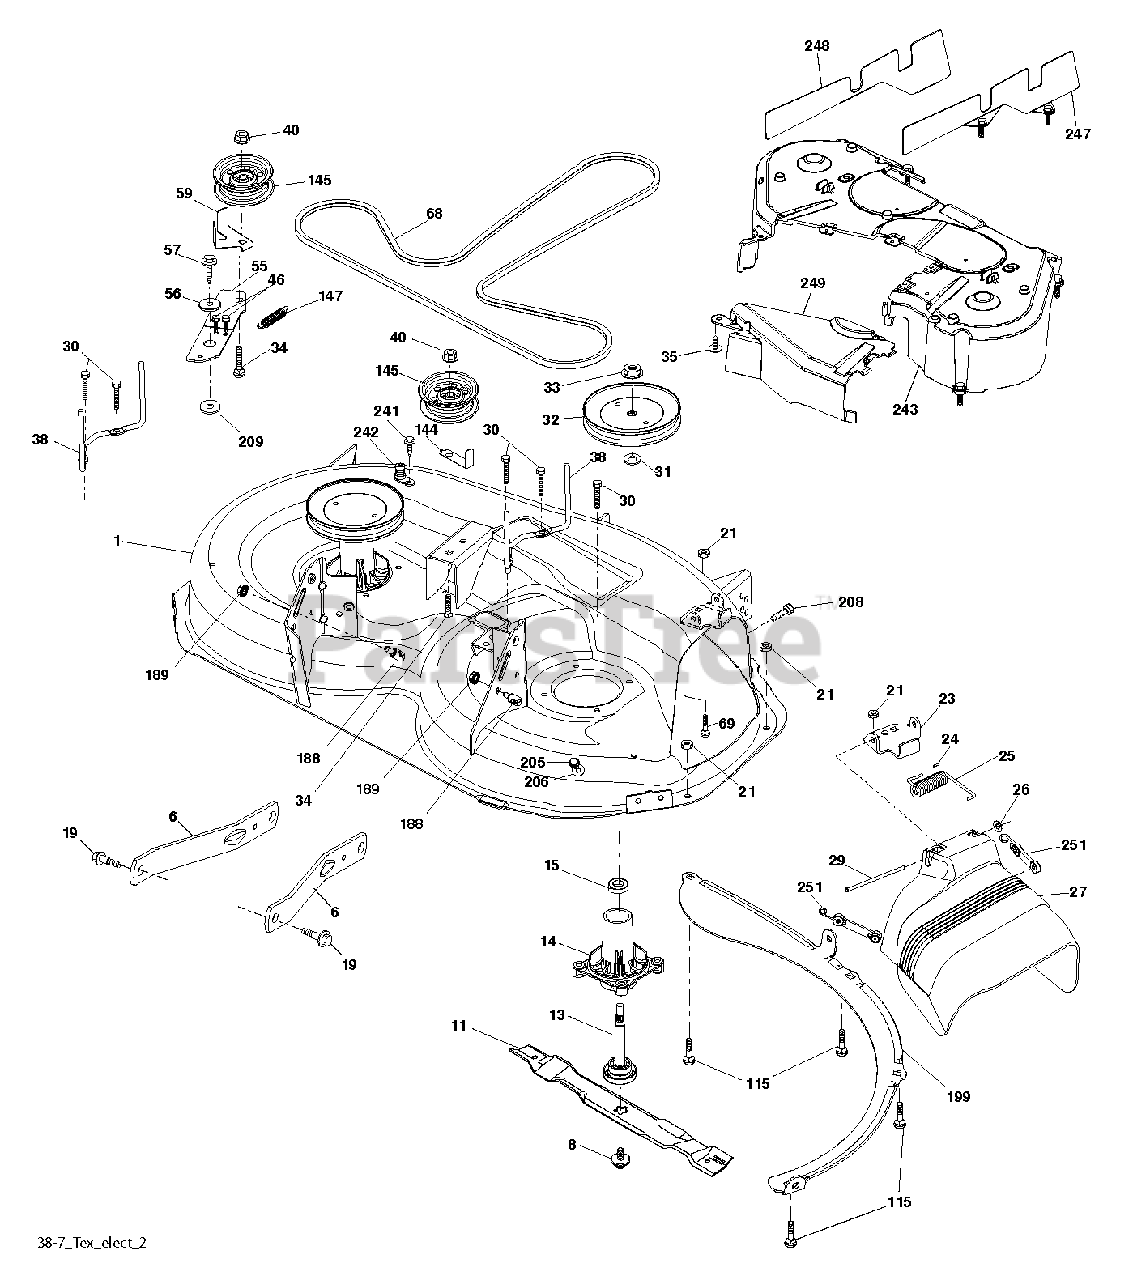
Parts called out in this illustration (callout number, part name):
1	DECK.WELD.38.NGW.TX.W/HOL.GREY
6	ARM.SUSPENSION.MOWER.R
8	BOLT.WASHER.ASM.7/16-2
11	BLADE 38" PREMIUM
13	SHAFT.ASM.MDRL.N/GREASE.38
14	HOUSING.MANDREL.4PT.
19	BOLT.SHOULDER
21	LOCKNUT
23	BRKT.DEFLECTOR.38"2005+
24	CAP-SLEEVE LT
25	SPRING.TORSION.DEFLECT
26	NUT PUSH M
27	SHIELD ASM.DFLCTR MWR.38-7"BLK
29	ROD.HINGE
30	SCREW, WASHER HEAD
31	WASHER.SPACER.MANDREL
32	PULLEY MANDREL
33	NUT.FLANGE.LOCK.TOP
34	BOLT.3/8-16X1.50
35	FASTENER.XMAS.TREE
38	KEEPER BELT LH MANDREL
40	NUT LOCK FLG 3/8-16 UNC
46	SCREW.1/4-20X5/8
56	SPACER.RETAINER
57	SCREW 3/8-16X1
59	GUARD, BELT
68	BELT BELT 38' ELEC. DECK
69	BOLT
115	BOLT
144	KEEPER BELT
145	PULLEY.IDLER.48"PRIMARY
147	SPRING.MOWER.DRIVE.ELECTRIC
188	STUD.FASTNER.W/ANTI-ROTATE
189	NUT LOCK HEX FLANGE 5/16-18
199	BAFFLE.VORTEX.FRONT.38"
205	SCREW
208	SCREW 3/8-16X1/2
209	WASHER 12/32X2X10GA
241	SCREW.TT.#10-32X.5.3/8.FLANGE
242	PORT.WASHOUT
247	SHIELD RIGHT
248	SHIELD LEFT
249	COVER CABLE CLUTCH
251	ELASTIC STRAP KIT
